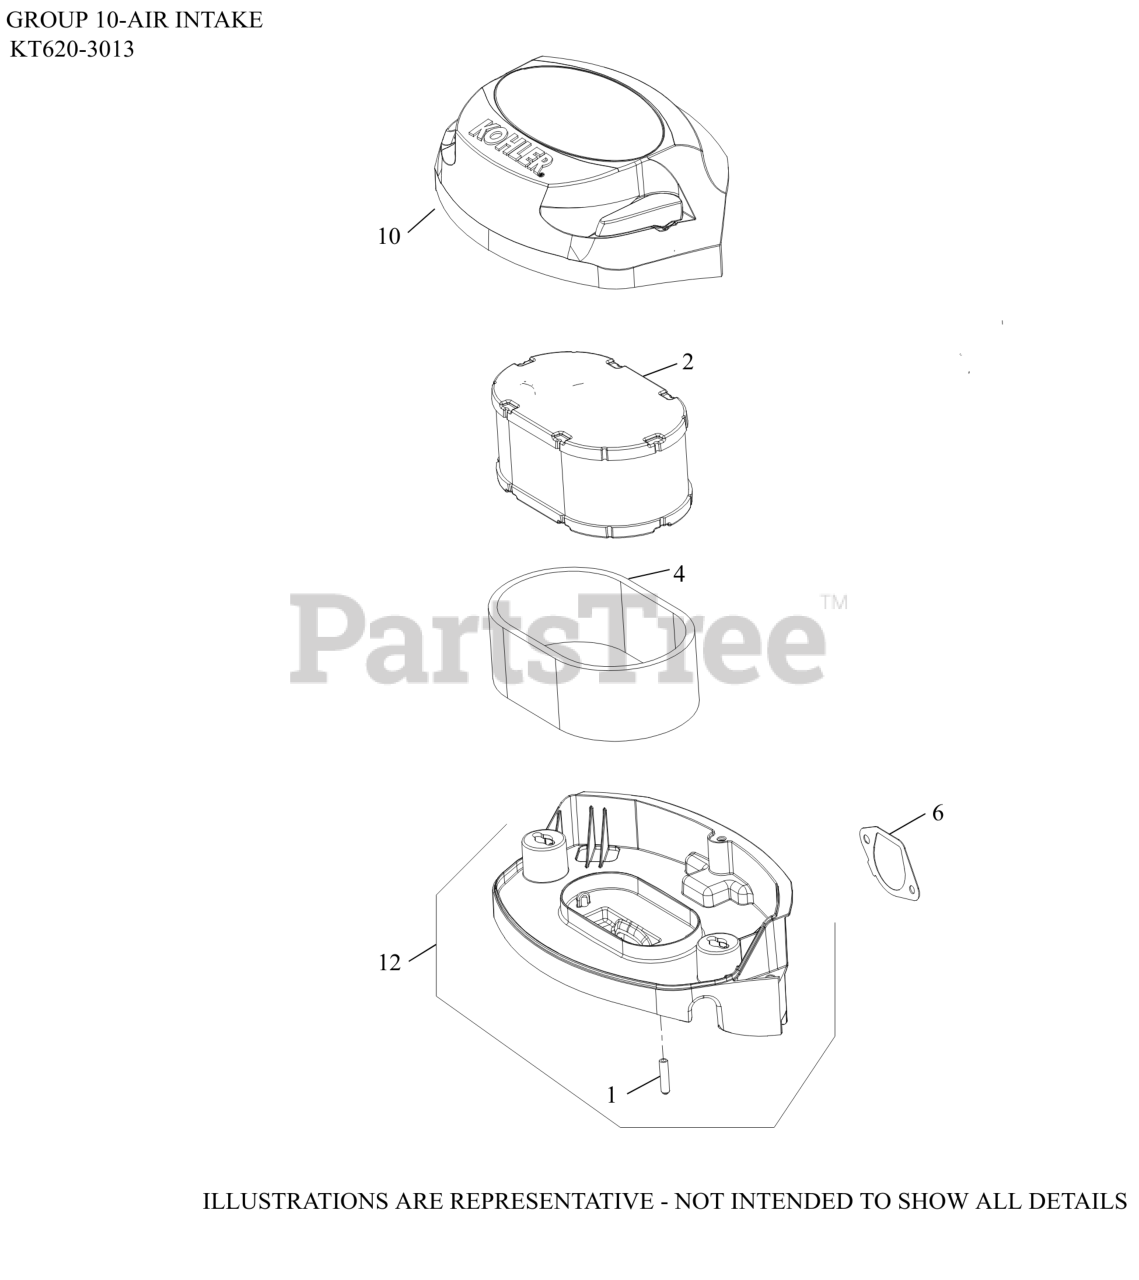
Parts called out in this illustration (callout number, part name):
1	CAP, MASKING
2	ELEMENT, AIR FILTER
4	ELEMENT, PRE-CLEANER
6	GASKET, AIR CLEANER BASE
10	COVER ASSY, AIR CLEANER
12	BASE ASSY, AIR CLEANER
